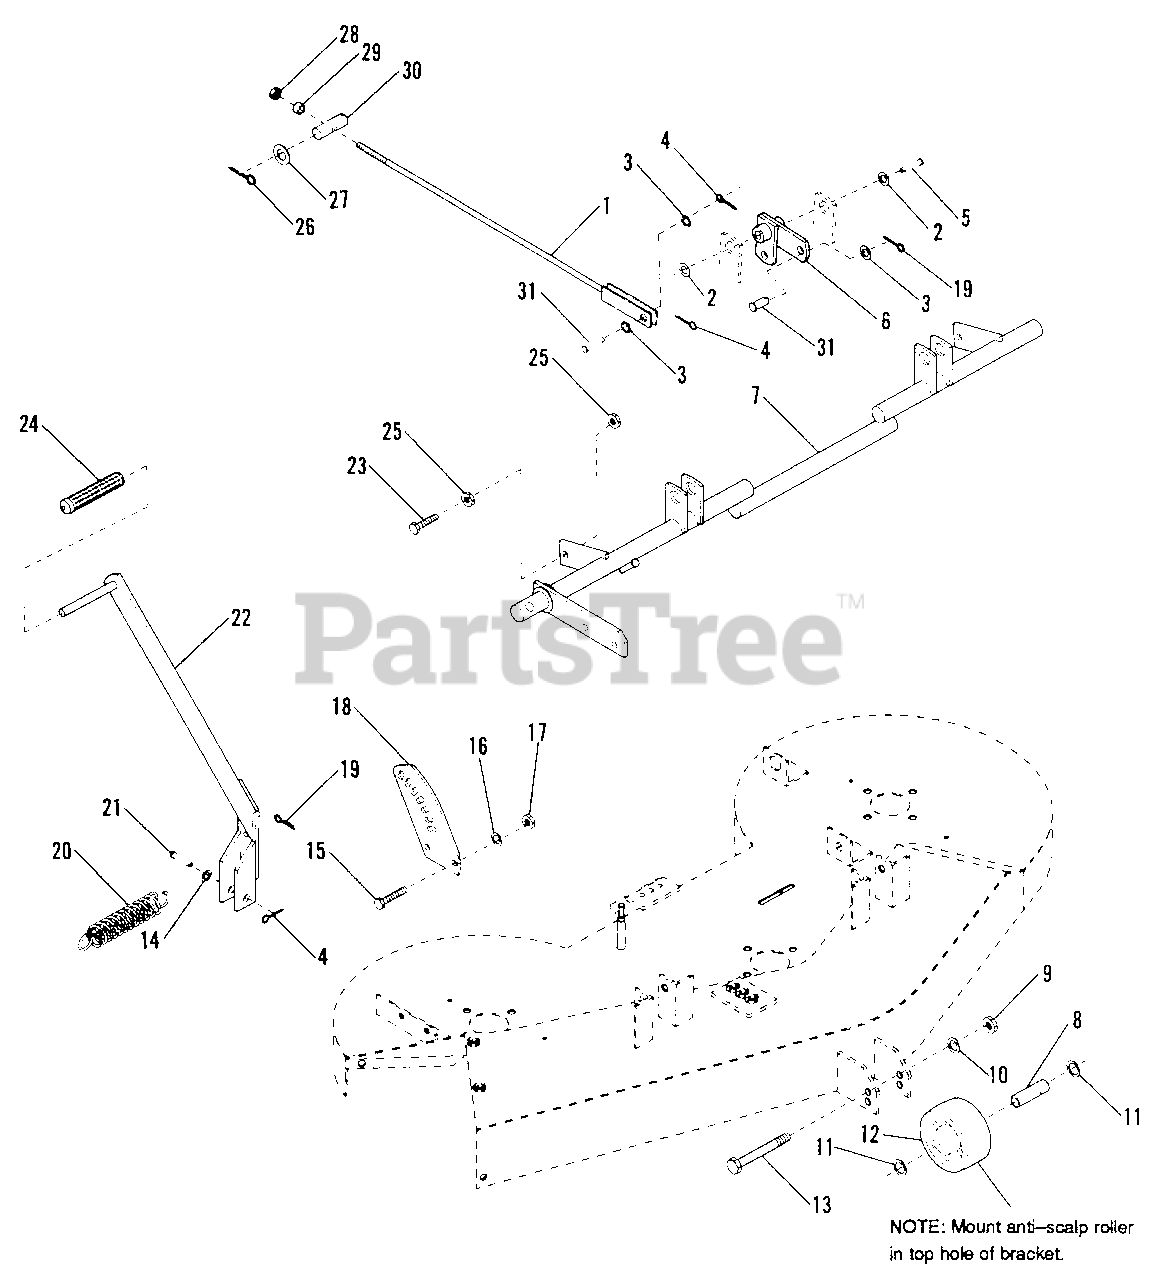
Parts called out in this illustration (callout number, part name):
1	ADJUSTING ROD ASSY. (1691847)
1	ADJUSTING ROD ASSY. (1691848 to 1691850)
2	WASHER, Plain
3	WASHER, Plain
5	CLEVIS PIN 1/2 x 2-3/4
6	HANGER ASSY.
7	SHAFT ASSY., Lift (1691847)
7	SHAFT ASSY., Lift (1691848)
7	SHAFT ASSY., Lift (1691849)
7	SHAFT ASSY., Lift (1691850)
8	SPACER (1691847)
8	SPACER (1691847) SPACER (1691848, 1691849)
8	SPACER (1691847) SPACER (1691848, 1691849) SPACER (1691850)
9	NUT, Hex 1/2-13 (1691847)
9	NUT, Hex 1/2-13 (1691847) NUT, Hex 1/2-13 (1691848, 1691849)
9	NUT, Hex 1/2-13 (1691847) NUT, Hex 1/2-13 (1691848, 1691849) NUT, Hex 1/2-13 (1691850)
10	LOCKWASHER, Spring 1/2 (1691847)
10	LOCKWASHER, Spring 1/2 (1691847) LOCKWASHER, Spring 1/2 (1691848, 1691849)
10	LOCKWASHER, Spring 1/2 (1691847) LOCKWASHER, Spring 1/2 (1691848, 1691849) LOCKWASHER, Spring 1/2 (1691850)
11	WASHER, Plain (1691847)
11	WASHER, Plain (1691847) WASHER, Plain (1691848, 1691849)
11	WASHER, Plain (1691847) WASHER, Plain (1691848, 1691849) WASHER, Plain (1691850)
12	WHEEL, Gauge, 4" Dia. (1691847)
12	WHEEL, Gauge, 4" Dia. (1691847) WHEEL, Gauge, 4" Dia. (1691848, 1691849)
12	WHEEL, Gauge, 4" Dia. (1691847) WHEEL, Gauge, 4" Dia. (1691848, 1691849) WHEEL, Gauge, 4" Dia. (1691850)
13	CAPSCREW, Hex 1/2-13 x 3-1/2 (1691847)
13	CAPSCREW, Hex 1/2-13 x 3-1/2 (1691847) CAPSCREW, Hex 1/2-13 x 3-1/2 (1691848, 1691849)
13	CAPSCREW, Hex 1/2-13 x 3-1/2 (1691847) CAPSCREW, Hex 1/2-13 x 3-1/2 (1691848, 1691849) CAPSCREW, Hex 1/2-13 x 3-1/2 (1691850)
14	WASHER, Plain
15	CAPSCREW, Hex 3/8-16 x 1-1/4
16	LOCKWASHER, Spring 3/8
17	NUT, Hex 3/8-16
18	PLATE, Height Adjusting
19	COTTER HAIRPIN
20	SPRING, Extension
21	CLEVIS PIN 1/2 x 2
22	HANDLE ASSY., Left
23	CAPSCREW, Hex 3/8-16 x 1-1/2
24	GRIP, Handle
25	NUT, Hex 3/8-16
26	COTTER PIN
27	WASHER, Plain
28	NUT, Fiber Lock 3/8-16
29	SPACER (1691847)
29	SPACER (1691848 to 1691850)
31	CLEVIS PIN 1/2 x 1-1/4
